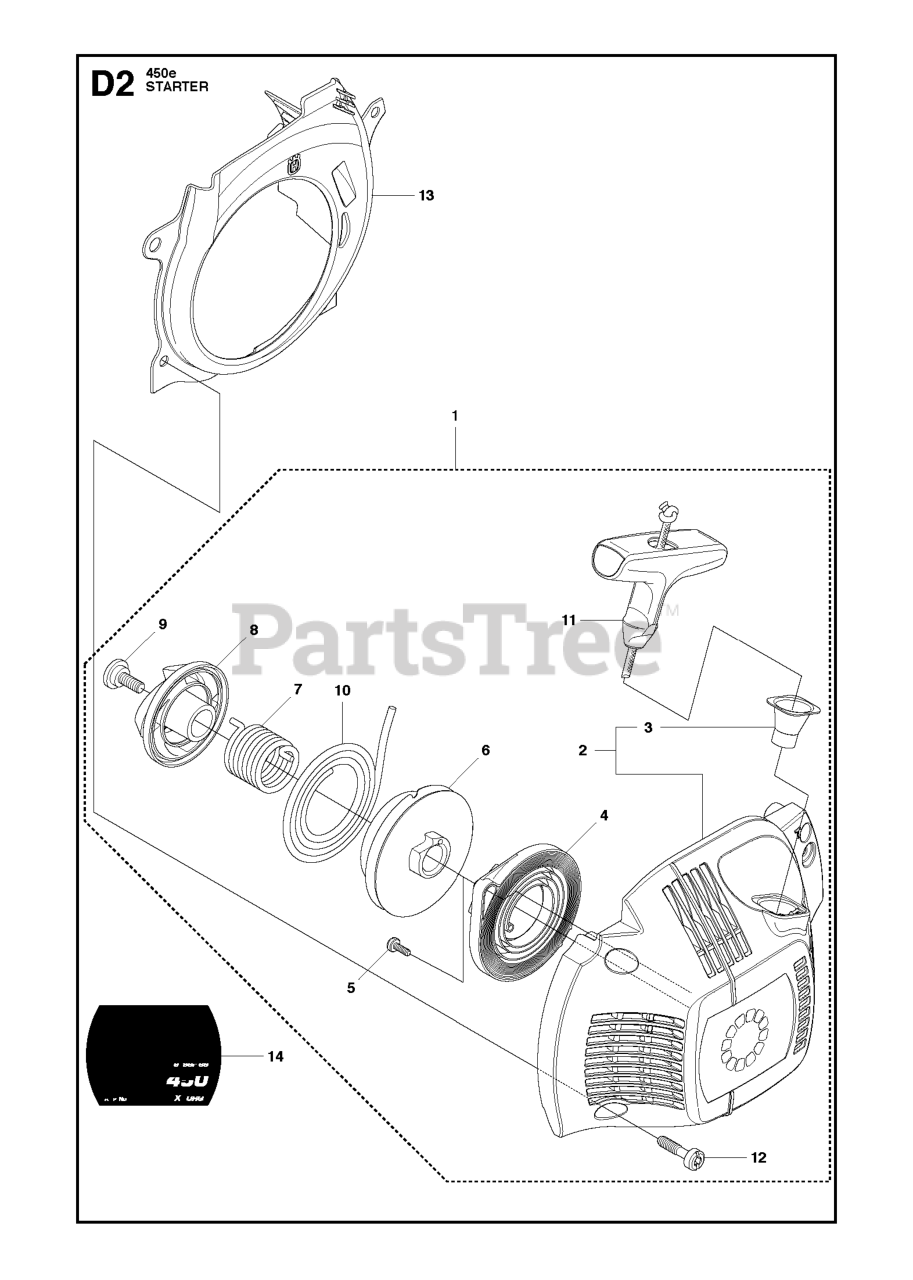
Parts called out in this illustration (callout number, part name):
1	STARTER ASSY
2	STARTER HOUSING
4	SPRING CASSETTE ASSY
6	STARTER PULLEY
10	STARTER ROPE
13	COOLING AIR CONDUCTOR
